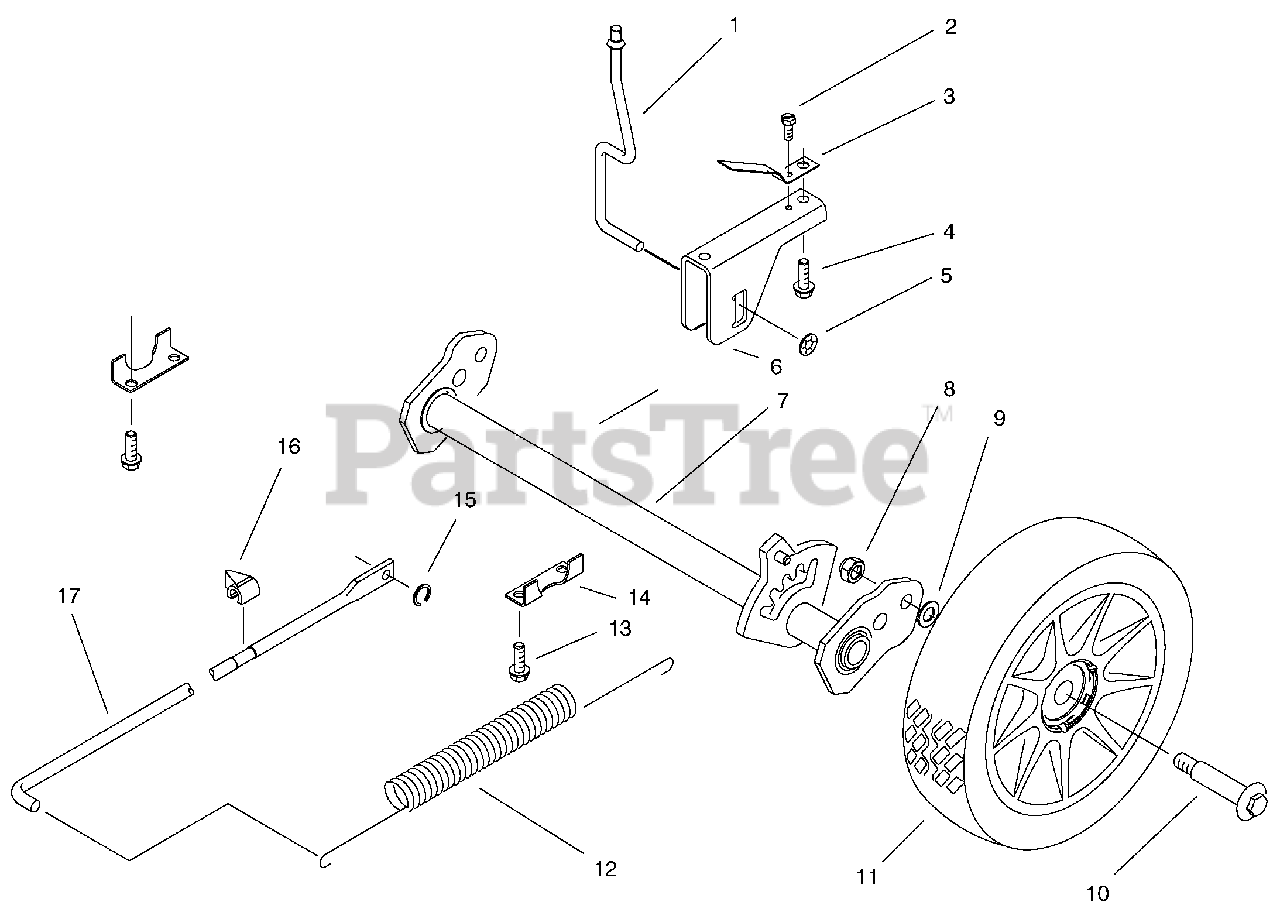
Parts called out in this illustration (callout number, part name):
1	Rod-Trigger
2	Screw-Tapping
3	Spring-Trigger Retainer
6	Saddle-H.O.C.
7	Arm-Pivot
8	Nut-Lock
10	Bolt-Shoulder
11	Wheel & Tire Assembly
12	Spring-Counterbalance
13	Screw-Tapping
14	Plate-Securing Rear
15	Ring-Grip
16	Indicator-H.O.C.
17	Rod-Link
